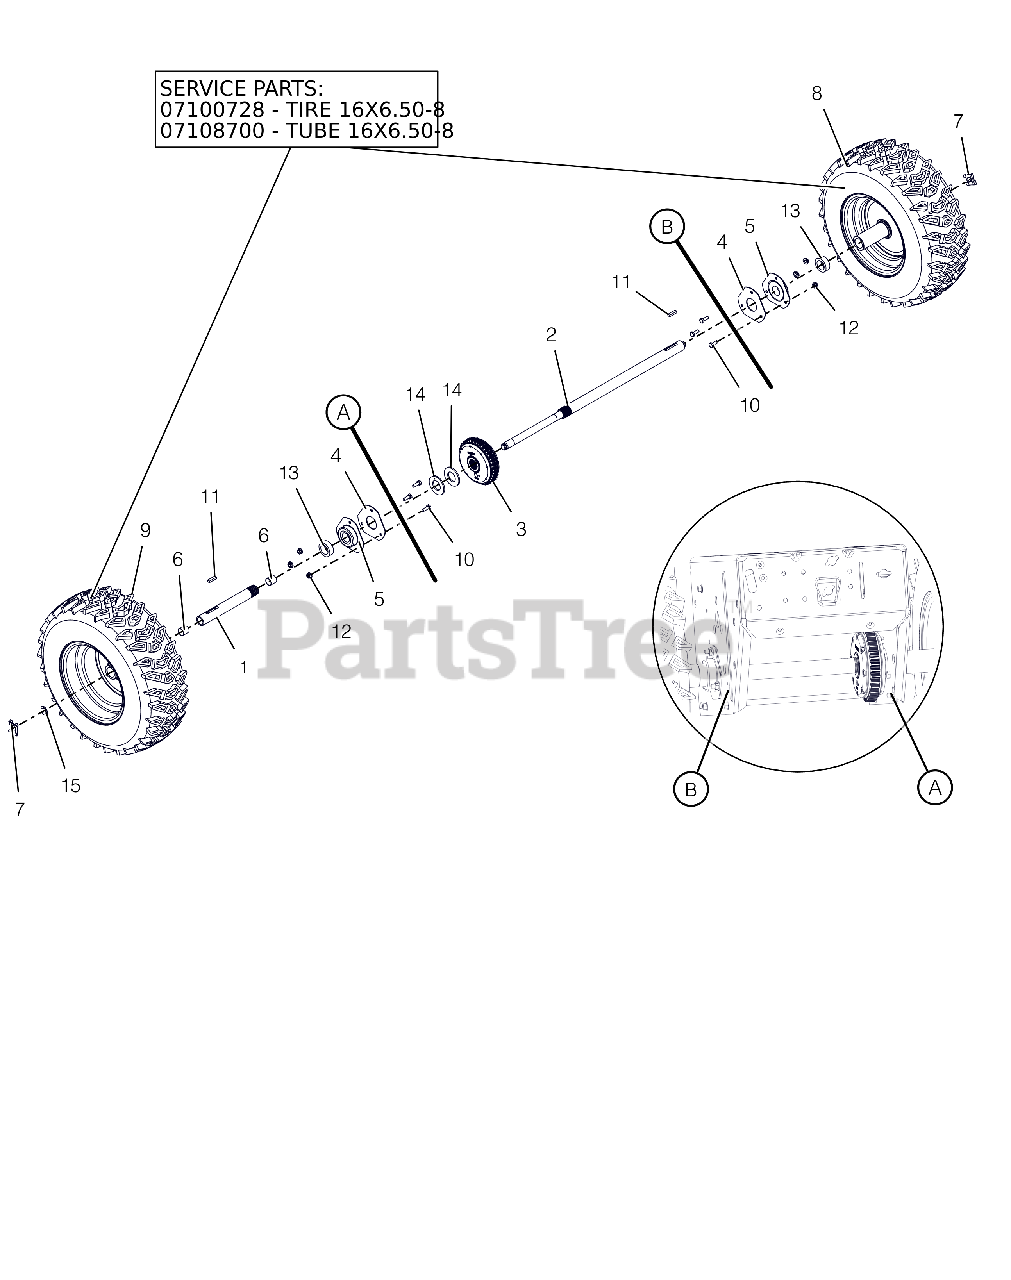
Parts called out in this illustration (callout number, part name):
1	AXLE, SHORT-AUTO W/BUSHINGS
2	AXLE, LONG-PRO AUTO DIFF
3	DIFFERENTIAL, AUTOMATIC
4	PLATE, BEARING SPACER
5	BRG-FLG 1.003/1.000 3 BOLT
6	BSHG-SLV .706X.764X.75 BRZ
7	CLIP, SNAP .625 DIA
8	TIRE/WHEEL,LH 16X6.5-8 DIFF T2
9	TIRE/WHEEL,RH 16X6.5-8 DIFF T2
10	@BLT-HEX .25-20X.75 GR5 YWZC
11	KEY-RECT .25X.188X1.00
12	@NUT-LK-CTR-FLG .25-20 YWZC
13	SPACER, PRO AXLE BEARING
14	WSHR-FL-STL- 1.062X2.0X.134 YZ
15	RG-RTNG-EXT .625X.042
16	TIRE, 16X6.50-8 K478
17	TUBE
